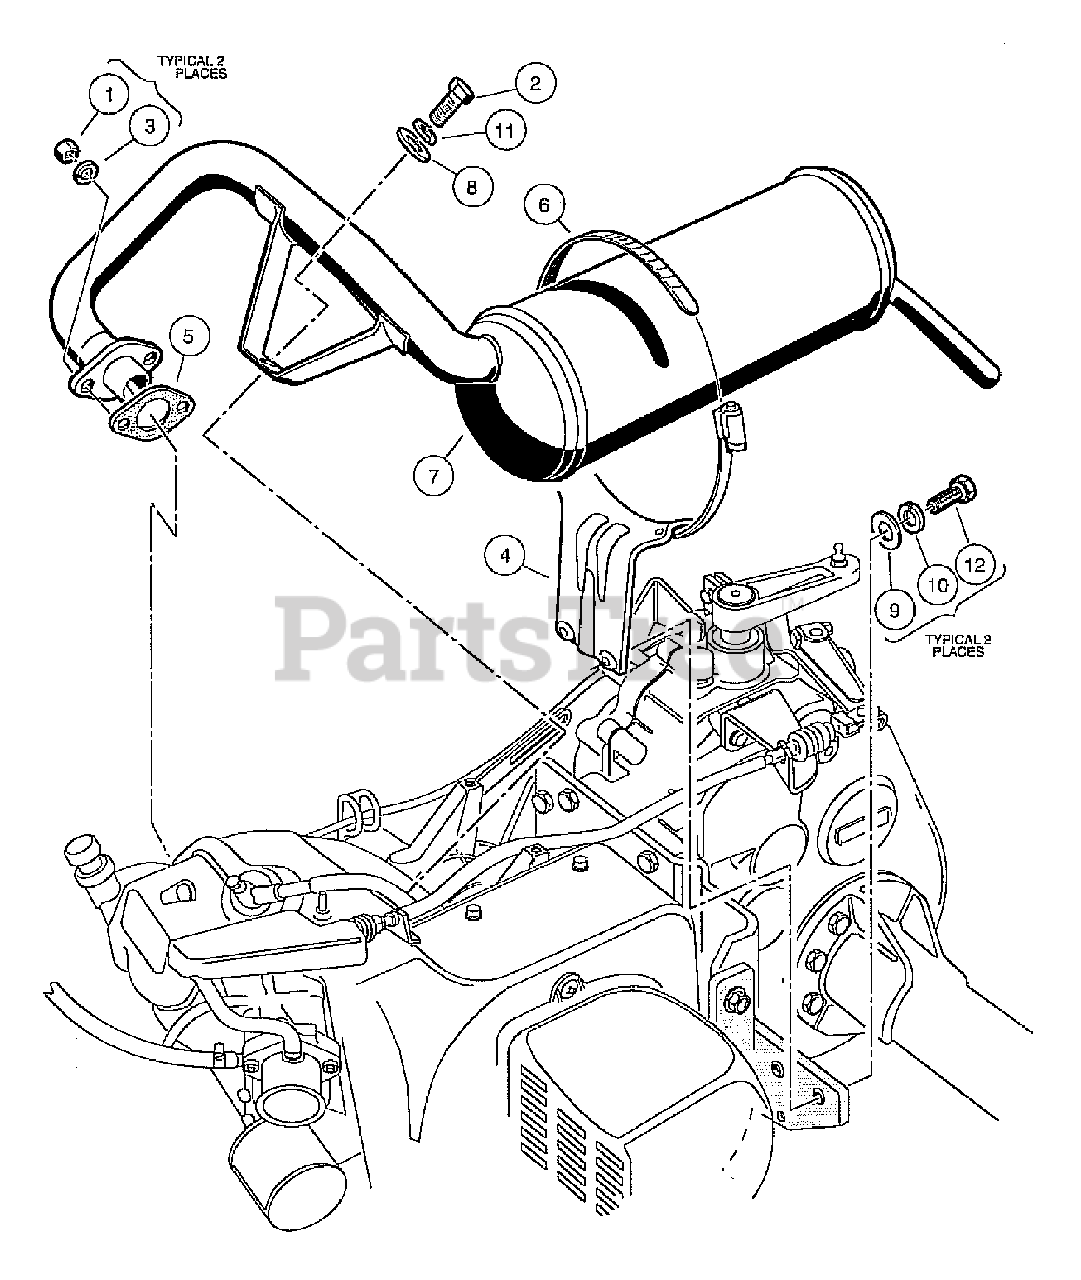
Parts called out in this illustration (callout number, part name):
1	Nut, M8-125 Hex
2	Screw, M8-125 X 22 Hex Gr.8.8
3	Lockwasher, 8mm Split
4	Bracket, Muffler Mounting
5	Gasket, Exhaust
6	Clamp, 5" Muffler Hose
7	Exhaust System, FE350
8	Washer, 5/16 Type A Flat
9	Washer, 1/4 Type A Narrow Flat
10	Lockwasher, 1/4 Helical Split
11	Lockwasher, 5/16 Split
12	Screw, 1/4-20 X 0.75 Hex-Head Cap
